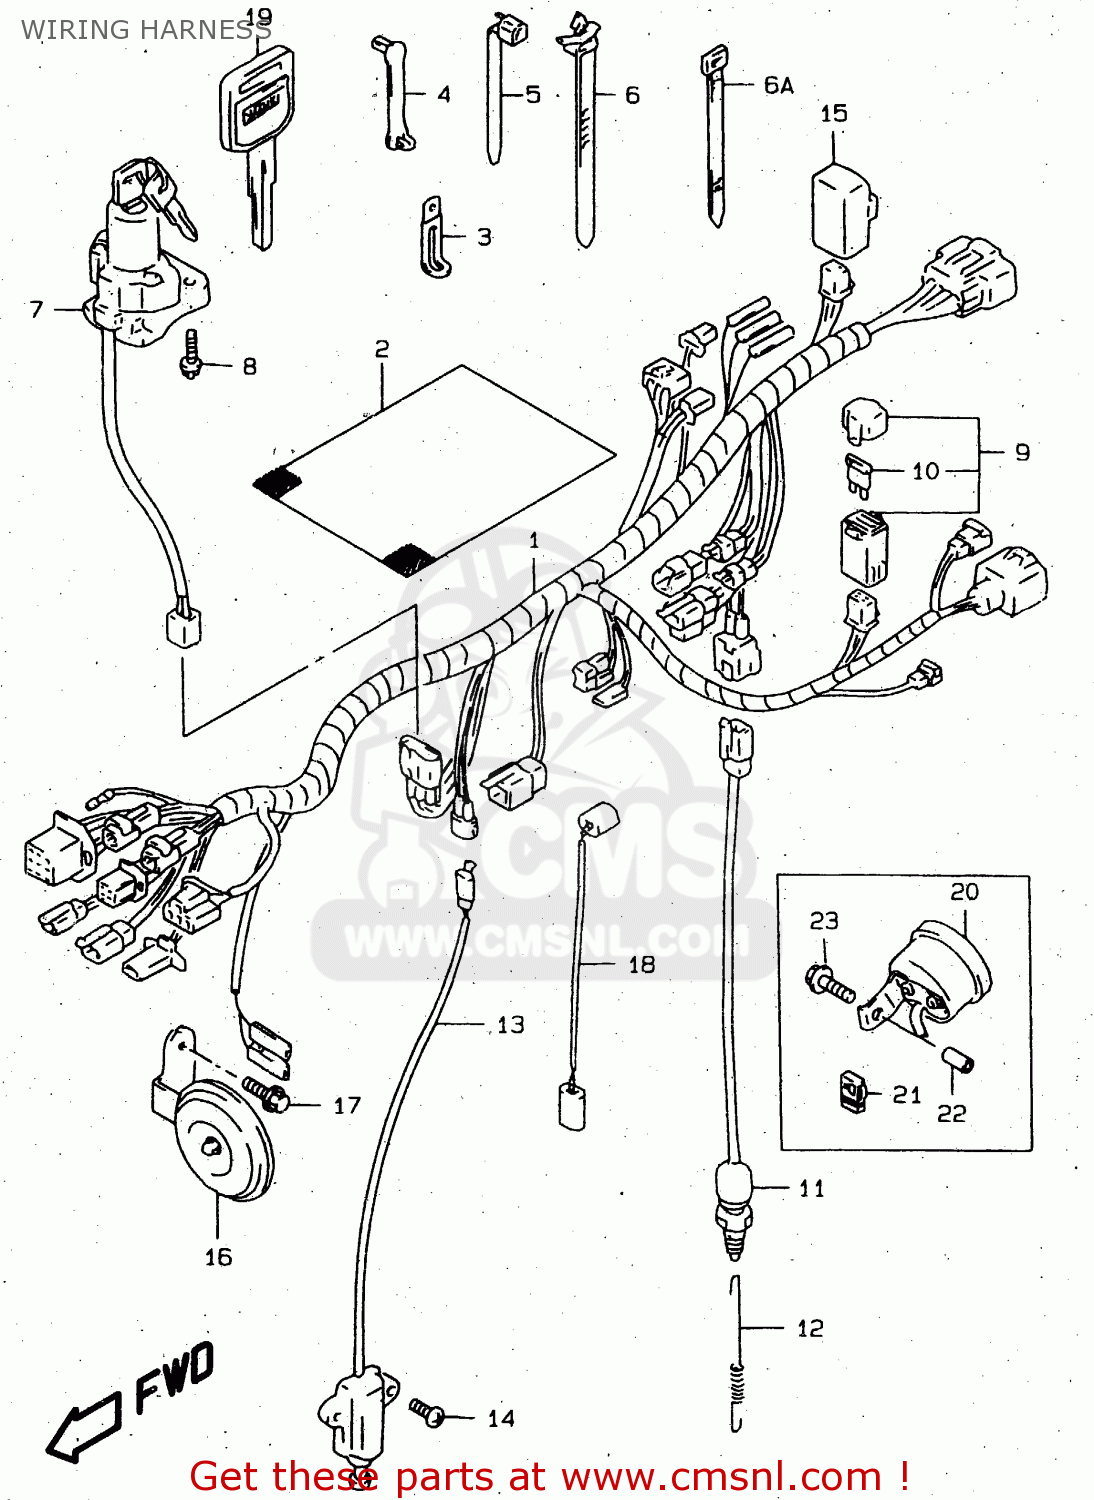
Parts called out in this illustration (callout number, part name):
1	HARNESS,WIRING
2	COVER,WIRING HARNESS
3	CLAMP(L:65)
4	CLAMP(L:33)
5	CLAMP(L:125)
6	CLAMP(L:90)
6A	CLAMP(L:120)
7	LOCK ASSY,STEERING
8	BOLT(8X20)
9	BOX ASSY,FUSE
10	FUSE(10A)
11	SWITCH ASSY,STOP LAMP
12	SPRING
13	SWITCH ASSY,SIDE STAND
14	SCREW 6X16
15	RELAY ASSY
16	HORN ASSY
17	BOLT
18	WIRE,THROTTLE SENSOR
19	KEY,BLANK
20	TACHOMETER ASSY
21	CONNECTOR,LEAD WIRE
22	SPACER(10.2X16X40)
23	BOLT, TACHOMETER
